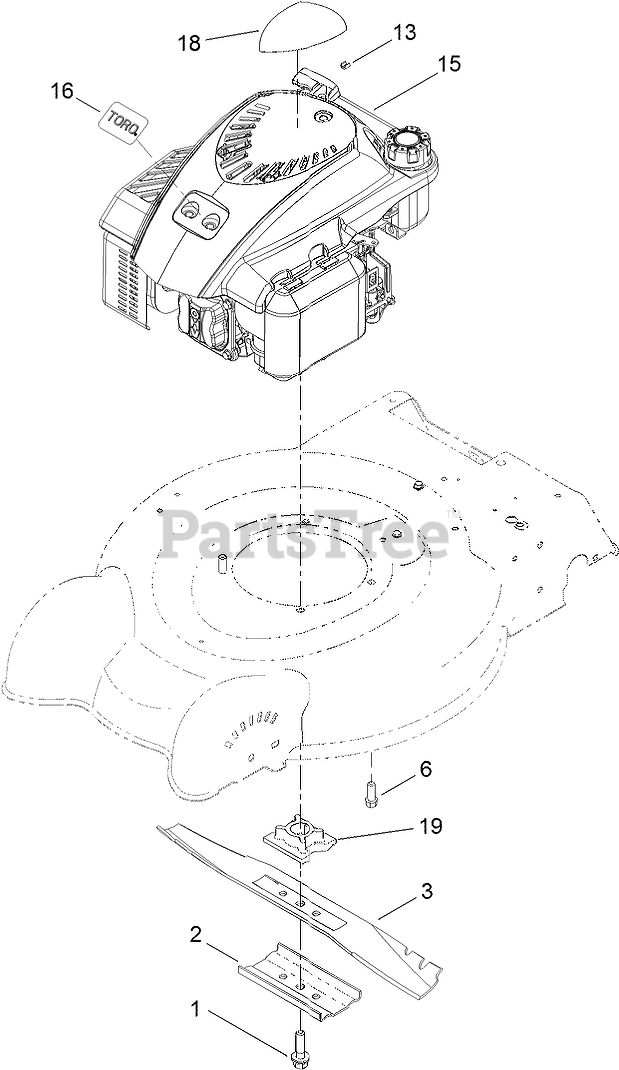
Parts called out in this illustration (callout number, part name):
1	BOLT-BLADE
2	SUPPORT-BLADE
3	BLADE-20 INCH
6	SCREW-TAPTITE
13	STOP-ROPE
15	ENGINE-LC1P65FA
16	PLATE-LOGO, TORO
18	DECAL-SHROUD
19	RETAINER-BLADE
